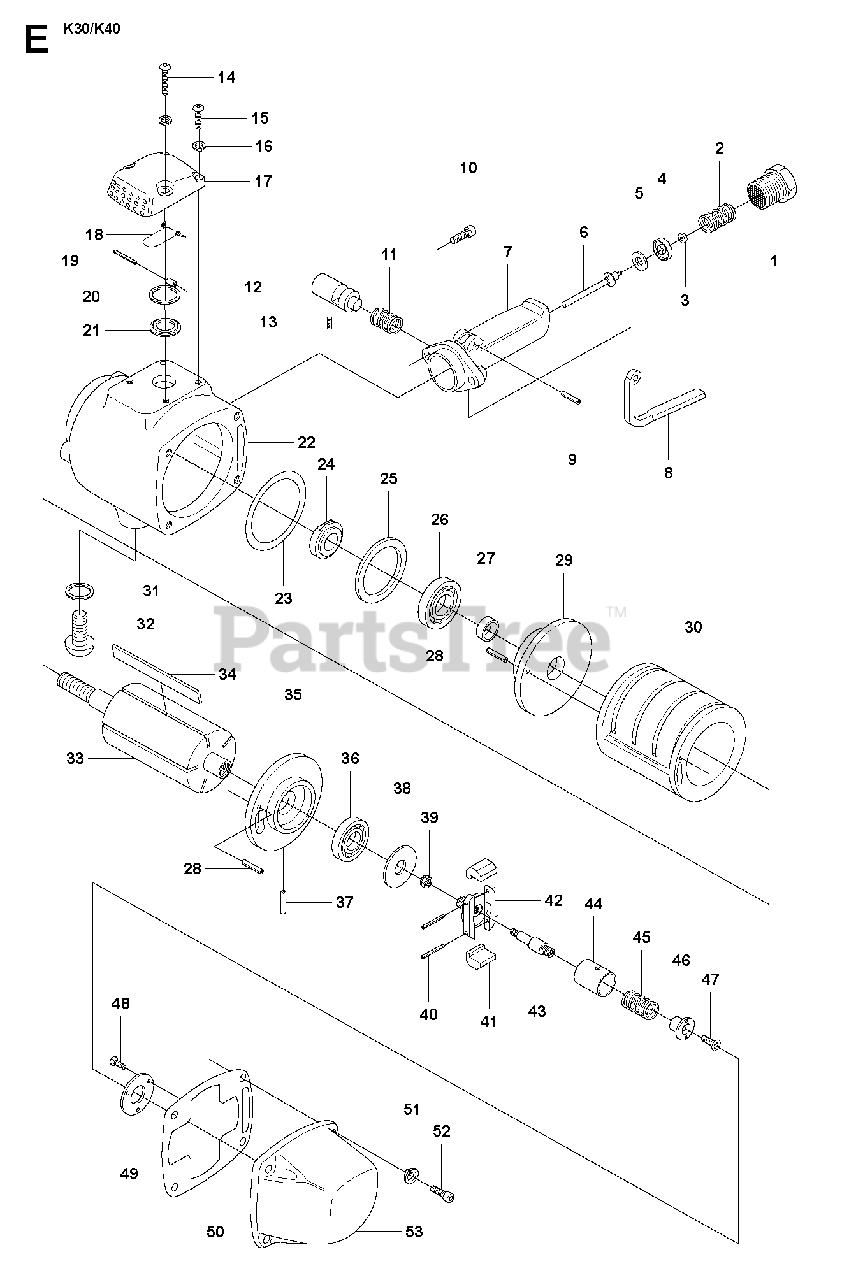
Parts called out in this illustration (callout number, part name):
15	SCREW IHSCM
36	BALL BEARING
51	SPRING WASHER
